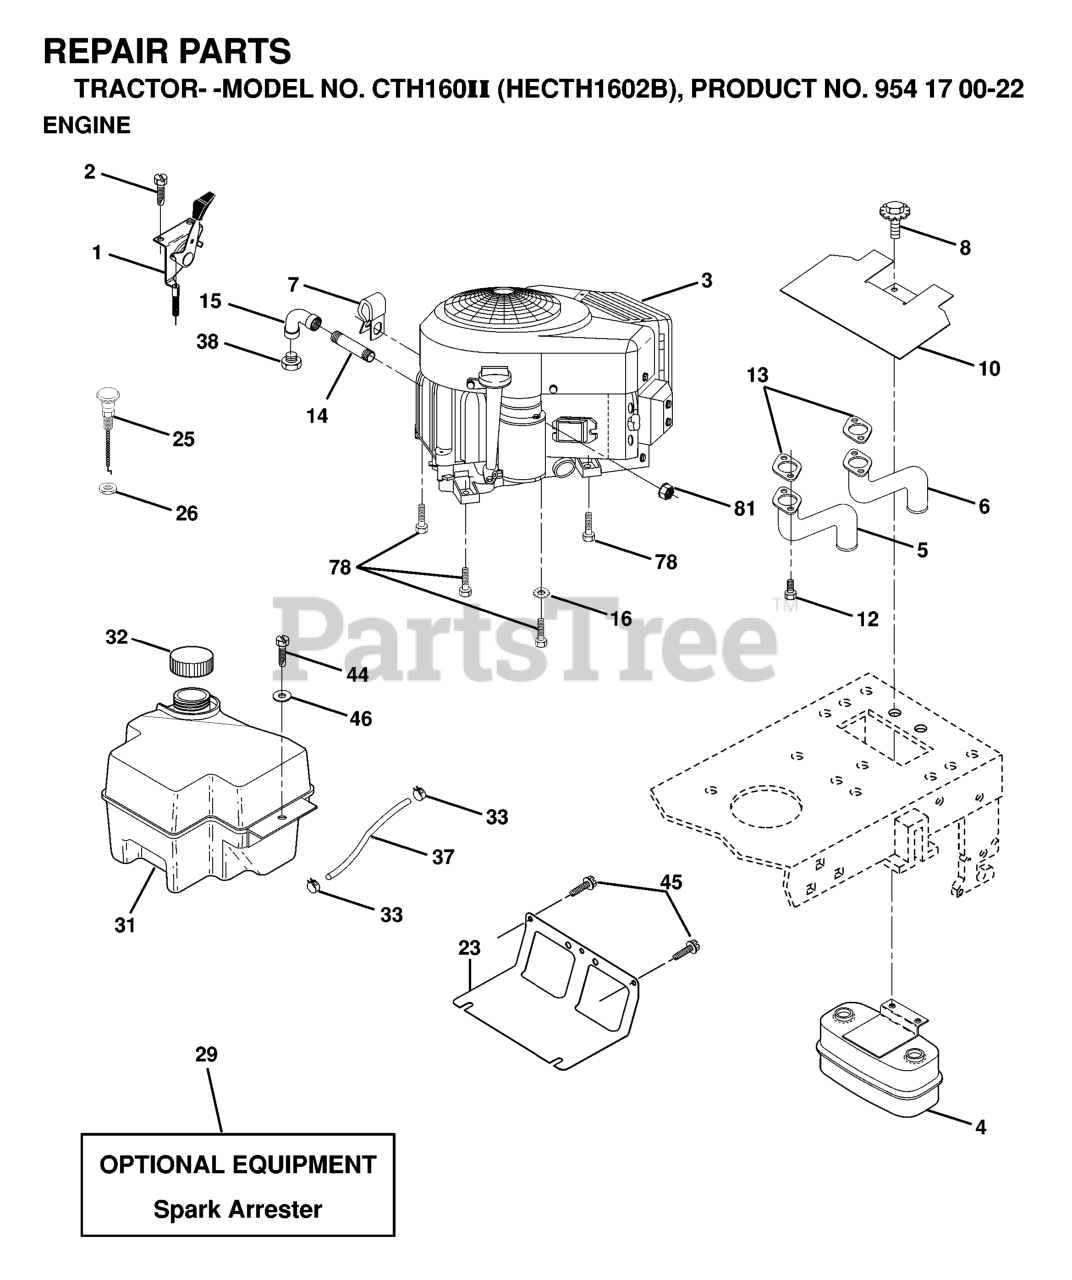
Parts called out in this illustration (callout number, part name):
1	CONTROL THROTTLE 36"
2	SCREW LT
4	MUFFLER.TWIN.CYL.LOW.TONE
5	TUBE ASSY EXH LH
6	TUBE ASSY EXH RH
8	BOLT HEX WASHER HD 5/16-18
10	SHIELD HEAT LT
14	Nipple, Pipe 3/8 NPT x 4-1/2
15	ELBOW
16	LOCKWASHER
25	CONTROL, CHOKE
26	Nut Keps 3/8 - 24 UNF
29	KIT.SPARK ARRESTOR 794945 B&S
31	FUEL TANK
32	FUEL CAP
33	HOSE CLAMP
37	LINE.FUEL.20
44	SCREW HEX CRT
45	SCREW, 3/8-16X3/4
78	SCREW.3/8-16
81	NUT
